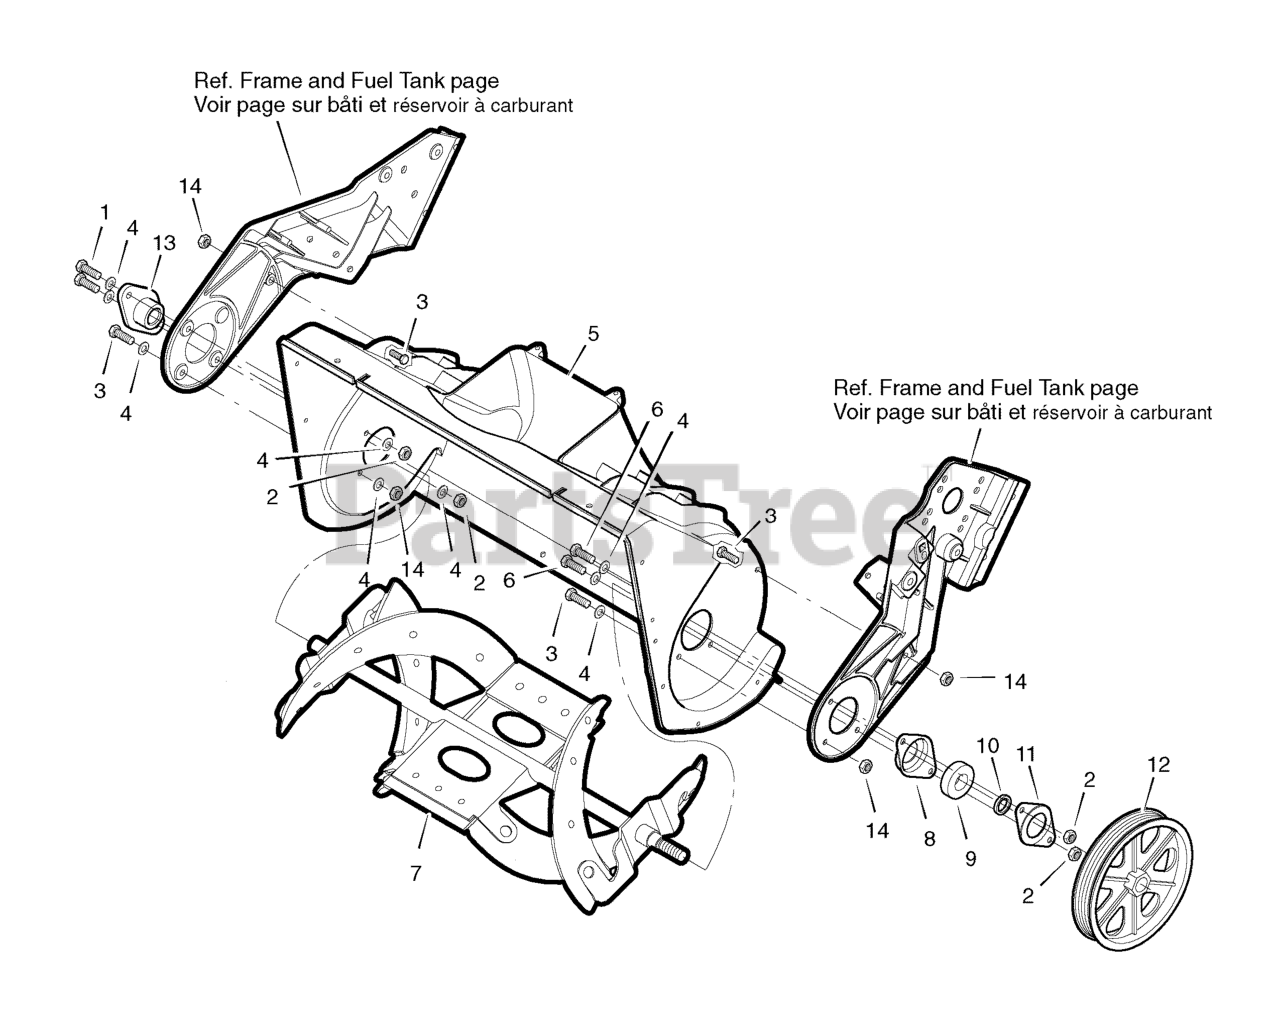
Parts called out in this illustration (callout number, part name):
1	Screw, 1/4-20 x 1.00
2	Nut, Hex 1/4-20
3	Screw, 1/4-20 x .75
4	Washer, Flat
5	Housing Assembly, Auger
6	Screw, 1/4-20 x .63
7	Auger Assembly, 22"
8	Retainer, Bearing
9	Bearing
10	Sleeve, Spacer
11	Plate, Bearing Retainer
12	Pulley, Auger Drive V6
13	Bearing, Flange
14	Nut, Centerlock 1/4-20
